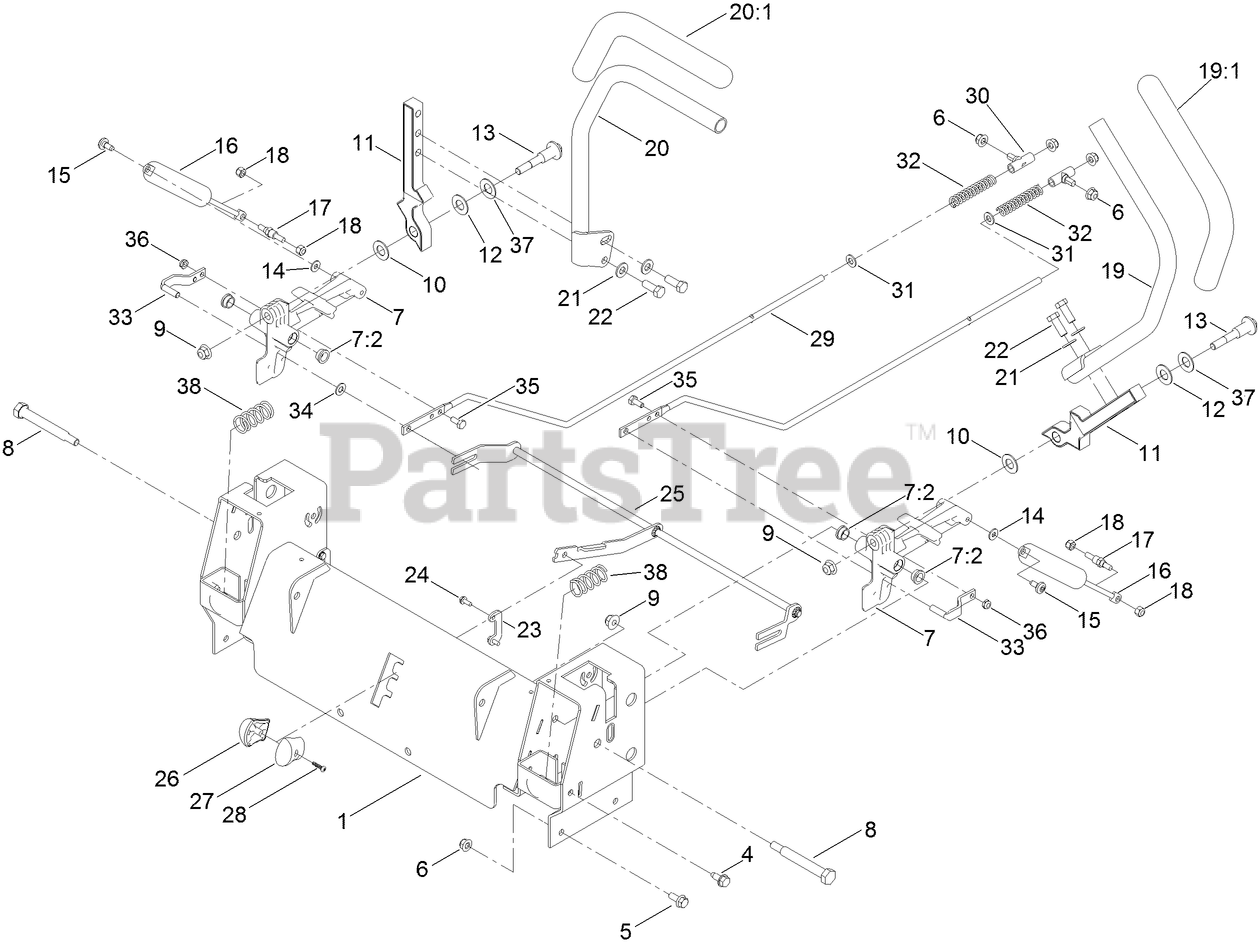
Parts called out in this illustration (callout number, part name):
1	CONTROL BOX ASM
4	SCREW-HWHTF
5	SCREW-HHF
6	NUT-HF, NI
7	ACTUATOR ARM ASM
7:2	BUSHING-FLANGE
8	BOLT-PIVOT
9	NUT-HF, NI
10	WASHER-NYLON
11	ARM-CONTROL
12	WASHER
13	BOLT-PIVOT
14	WASHER
15	SCREW-SHOULDER
16	DAMPER
17	STUD-DAMPER
18	NUT-LOCK, NI
19	HANDLE-CONTROL, LH
20	HANDLE-CONTROL, RH
21	WASHER-FLAT
22	SCREW-HH
23	RETAINER
24	SCREW-TAPTITE
25	SPEED CONTROL ASM
26	KNOB-RH
27	KNOB-LH
28	SCREW-PPH
29	ROD-HYDRO
30	MOUNT-ROD, HYDRO
31	WASHER-PLAIN
32	SPRING-RETURN, NEUTRAL
33	PIN-ROD, HYDRO
34	SPACER-NYLON
35	SCREW-HH
36	NUT-LOCK, NI
37	WASHER-BELLEVILLE
38	SPRING-RETURN
